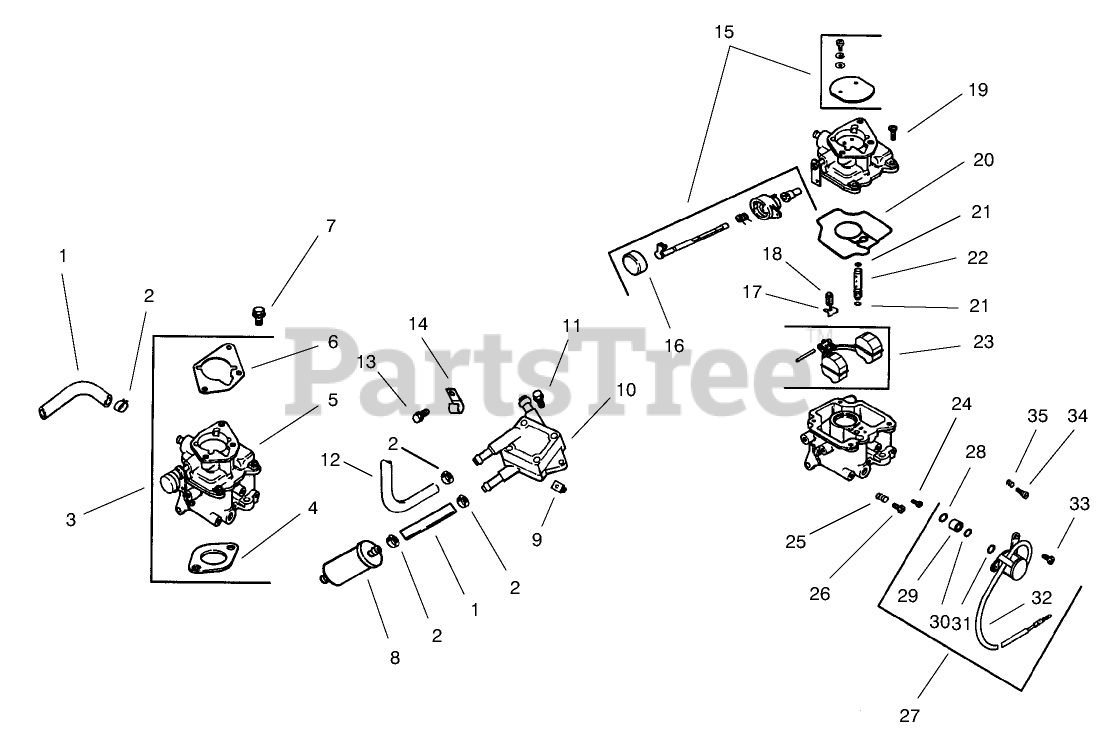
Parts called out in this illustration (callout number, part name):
1	Line-Fuel
2	Clamp
3	Kit, carburetor w/gasket (Includes 4-6)
4	Gasket-Air Cleaner
5	Carburetor assembly (Includes 15-35)
6	Gasket-Carburetor
7	Screw
8	Filter-Fuel
9	Nut
10	Pump-Fuel
11	Screw
12	Line, fuel17"
13	Screw
14	Clip-Cable (Only On: 72103)
15	Kit-Choke Repair (Incl. Ref. #33
16	Cap-Choke Lever Carburetor Assembly (Incl. Ref. #1-25 32)
17	Clip-Inlet Needle Valve
18	Valve-Inlet Needle
19	Screw
20	Gasket-Carburetor Body
21	ORing
22	Jet-Slow
23	Kit-Float Repair
24	Jet-Main
25	Spring-Idle Speed Adjust
26	Screw-Idle Speed Adjust
27	Kit-Solenoid Assembly
28	ORing
29	Seat-Solenoid
30	ORing
31	ORing
32	Solenoid
33	Screw
34	Needle-Idle Adjust
35	Spring-Idle Adjust
